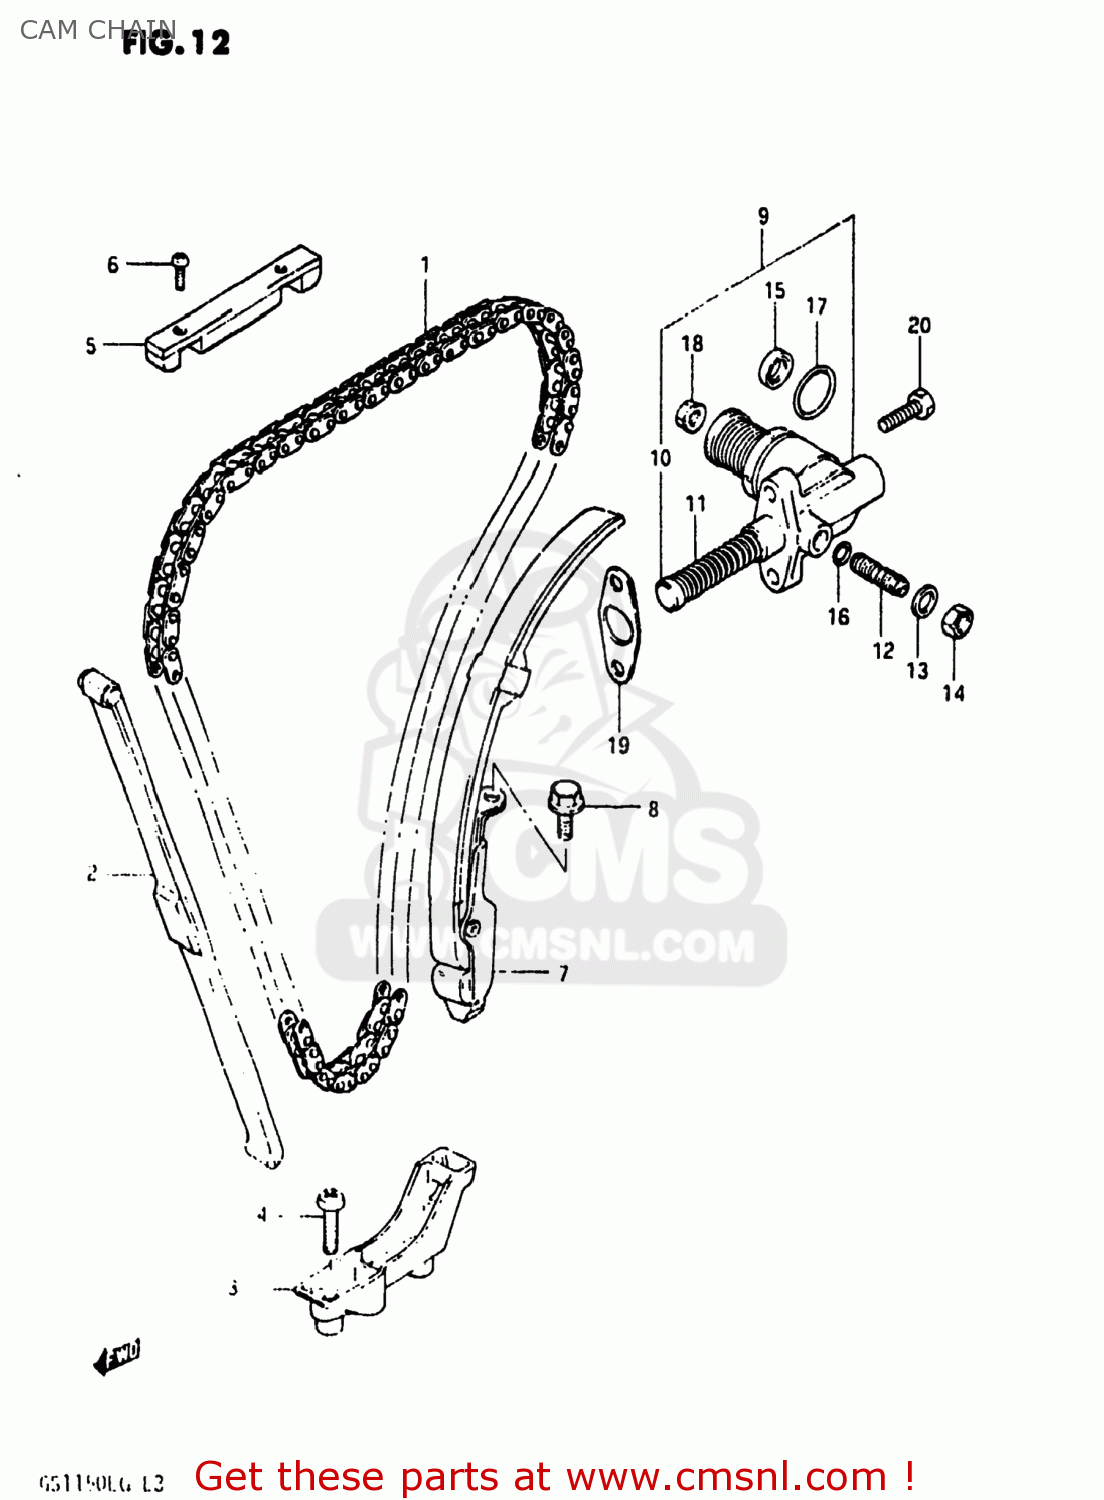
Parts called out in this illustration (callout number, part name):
1	CHAIN,CAMSHAFT DRIVE
2	GUIDE,CAM CHAIN NO.1
3	HOLDER,CAM CHAIN GUIDE
4	SCREW
5	GUIDE,CAM CHAIN
6	SCREW
7	TENSIONER,CAM CHAIN
8	BOLT
9	ADJUSTER ASSEMBLY,TENSIONER
10	ROD,PUSH
11	SPRING
12	SCREW,TENSIONER ADJUST
13	WASHER,8.5X16X
14	NUT
15	SEAL,OIL(10X16X4)
16	O RING(D:1.9,ID:5.7)
17	O RING(D:2.4,ID:20.8)
18	NUT 6MM
19	GASKET,TENSIONER ADJUSTER (MCA)
20	SCREW
